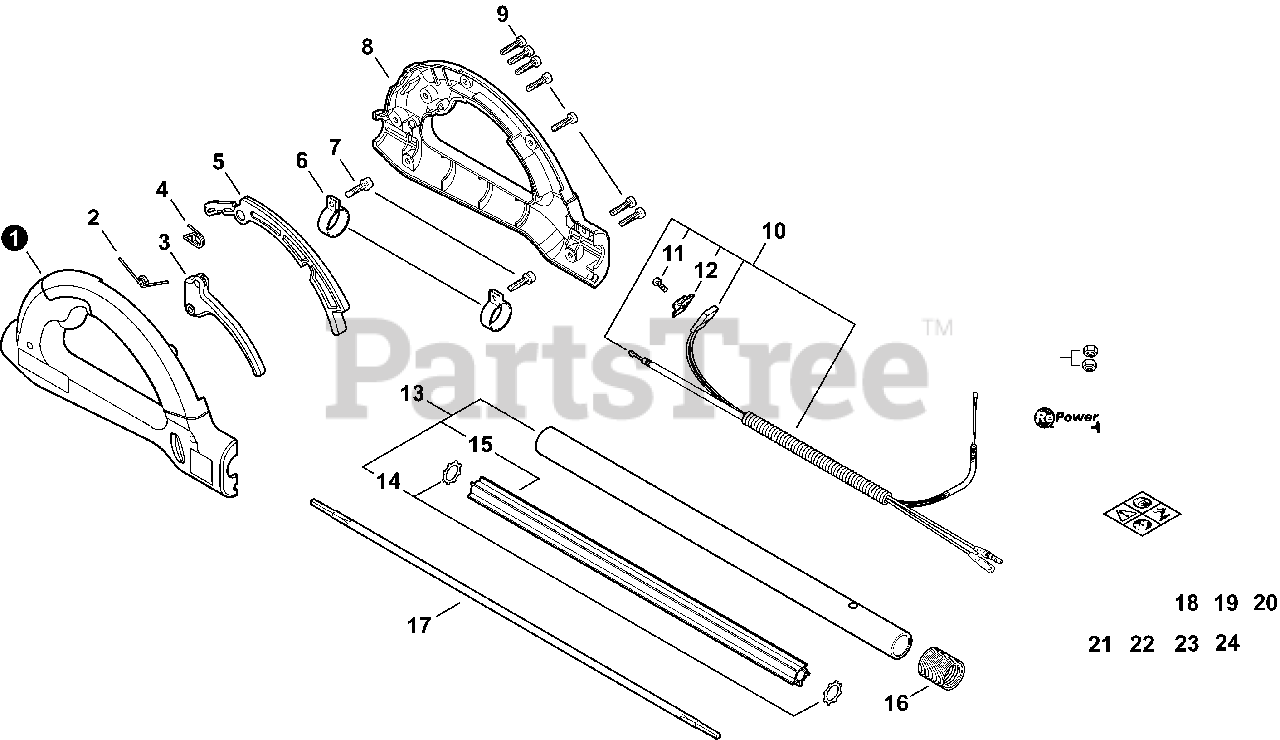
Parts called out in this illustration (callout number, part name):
1	BODY, HANDLE - LEFT
2	SPRING, TORSION
3	TRIGGER, THROTTLE
4	SPRING, TORSION
5	LOCKOUT, THROTTLE
7	SCREW M5×20
8	BODY, HANDLE - RIGHT
9	SCREW M5×18
10	CABLE ASSY, CONTROL
11	SCREW 3×10
12	KNOB, SWITCH - ORANGE
13	MAIN PIPE ASSY
16	TUBE, FLEXIBLE
17	DRIVESHAFT - FLEXIBLE
